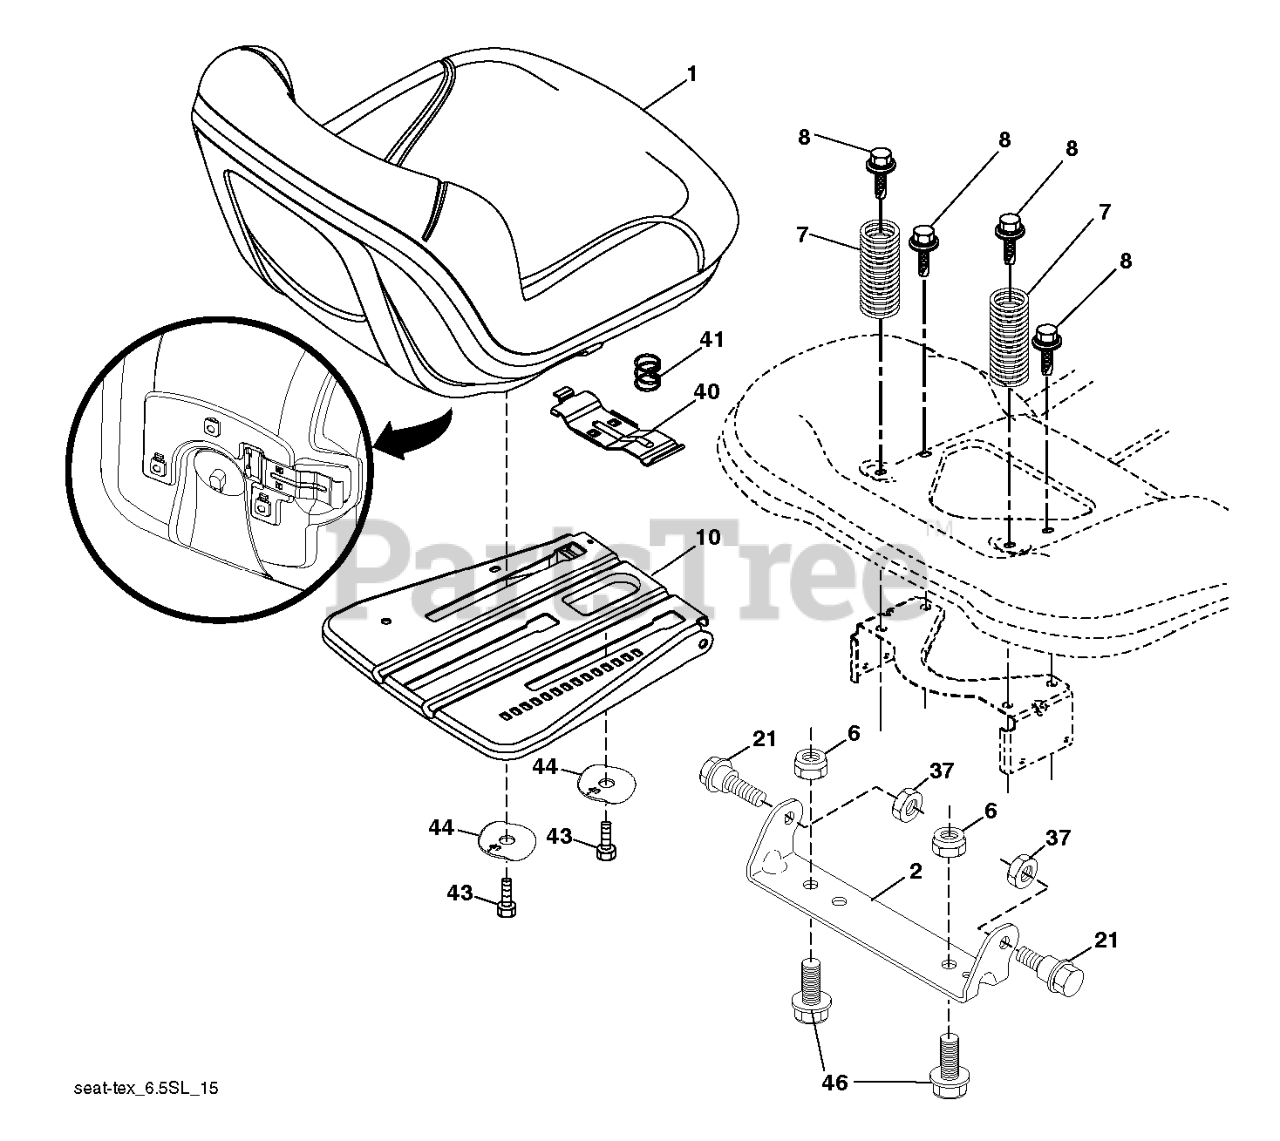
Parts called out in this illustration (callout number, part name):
1	CLUTCH COVER
2	BALL BEARING 6202-2RS1
3	RETAINING RING SGH 35
6	SCREW MC6LS 5X12
7	CLUTCH DRUM ASSM.
8	CLUTCH CPL
10	SCREW
14	CLUTCH SPRING
